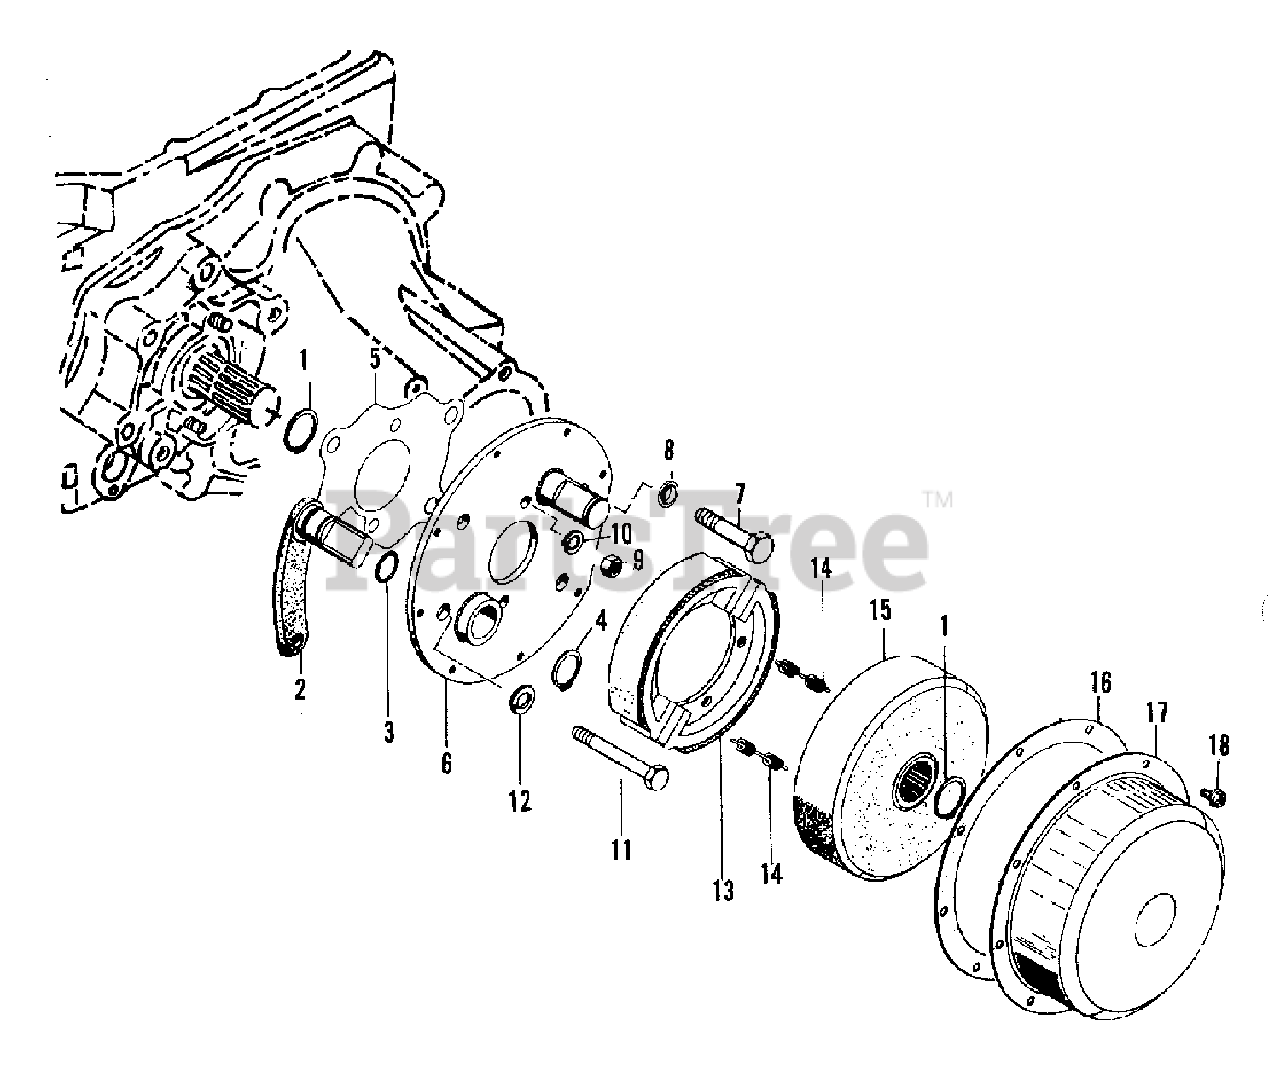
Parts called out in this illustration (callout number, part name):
1	RING, M30, snap-external
2	CAM L.H., brake
4	RING, M25, snap-external
6	PLATE, L.H., brake
7	SCREW, M12 x 55
8	WASHER, M12, seal
10	LOCKWASHER, M10
11	CAPSCREW, M12 x 85
12	LOCKWASHER, M12
13	SHOE ASSEMBLY, brake
14	SPRING, return
15	DRUM, brake
17	COVER, brake
18	SCREW, M6 x 12, w/lockwasher
